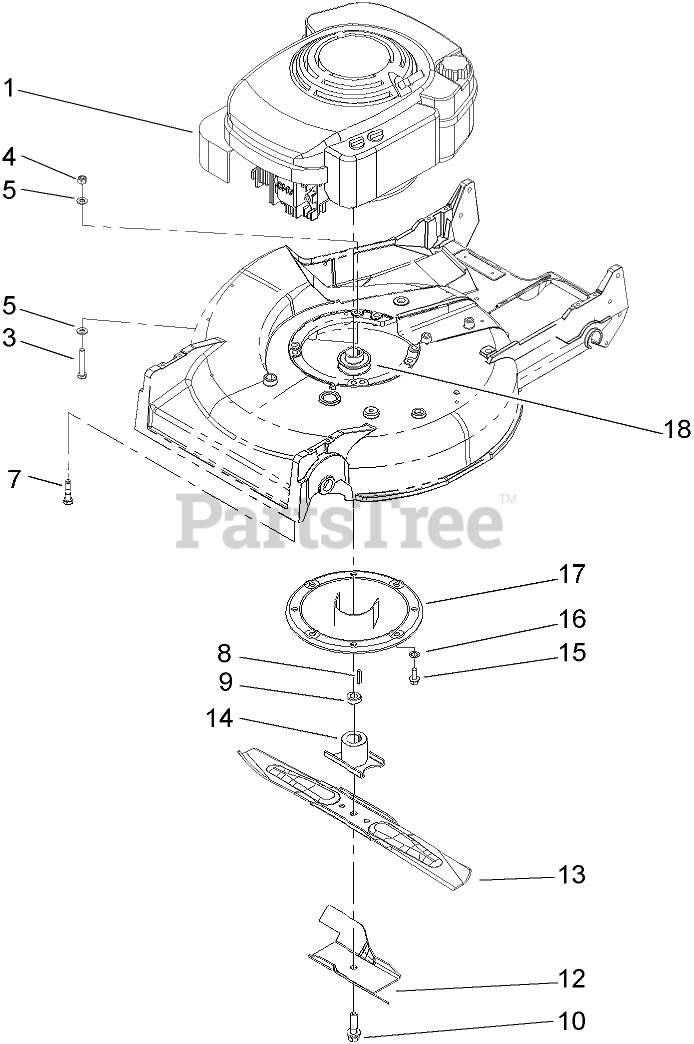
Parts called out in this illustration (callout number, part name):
3	SCREW-HH
4	NUT-LOCK, NI
5	WASHER-PLAIN
7	SCREW-SHOULDER
8	KEY-SQUARE
9	Spacer-Retainer, Blade
10	BOLT-BLADE
12	STIFFENER-BLADE
13	BLADE-21 INCH
14	RETAINER-BLADE
15	SCREW-HWHTF
16	WASHER-LOCK, INTERNAL
17	PROTECTOR-CRANKSHAFT
18	PULLEY-DRIVER
